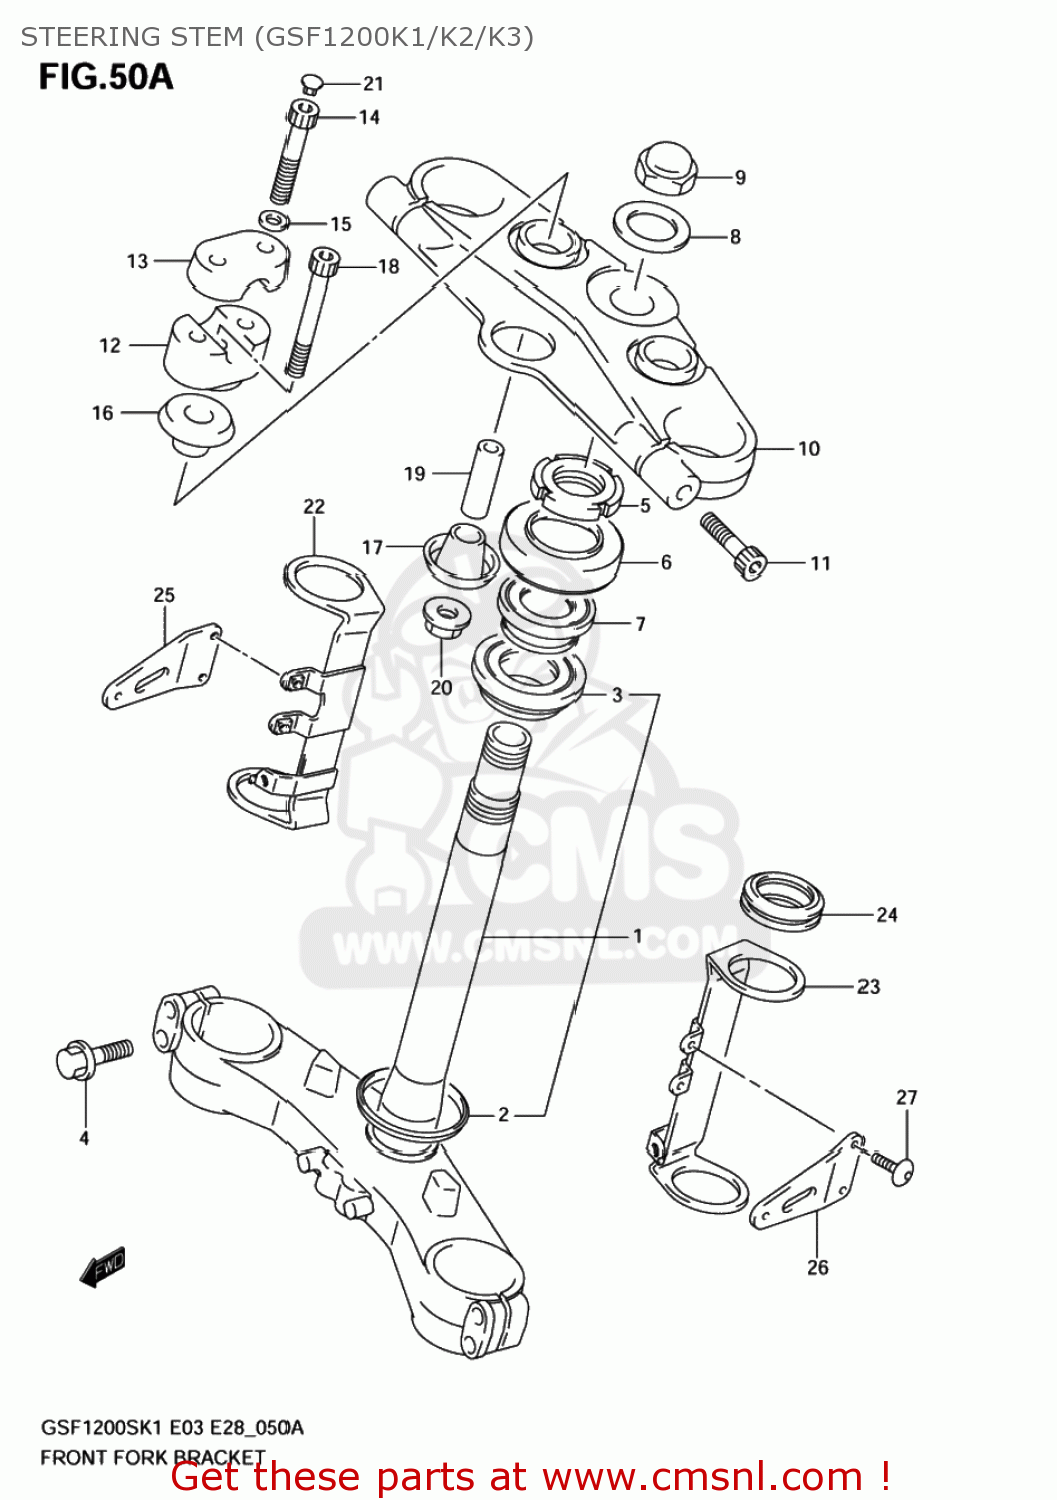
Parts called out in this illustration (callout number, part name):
1	STEM,STEERING
2	SEAL,STEERING LWR
3	BEARING(30X55X17)
4	BOLT
5	NUT,STEERING STEM
6	DUST SEAL,STEERING UPR
7	BEARING(25X47X15)
8	WASHER(22.5X32X1.6)
9	NUT,CAP
10	HEAD,STEERING STEM
11	BOLT
12	HOLDER,HANDLE UNDER
13	HOLDER,HANDLE UPR
14	BOLT
15	WASHER
16	CUSHION,RUBBER UPR
17	CUSHION,RUBBER UNDER
18	BOLT,HANDLE HOLDER(10X70)
19	SPACER
20	NUT
21	CAP(OD:11)
22	BRACKET,HEADLAMP HOUSING,R
23	BRACKET,HEADLAMP HOUSING,L
24	DAMPER,HEADLAMP HSG BRACKET
25	STAY,HEADLAMP HOUSING,R
26	STAY,HEADLAMP HOUSING,L
27	SCREW(6X12)
